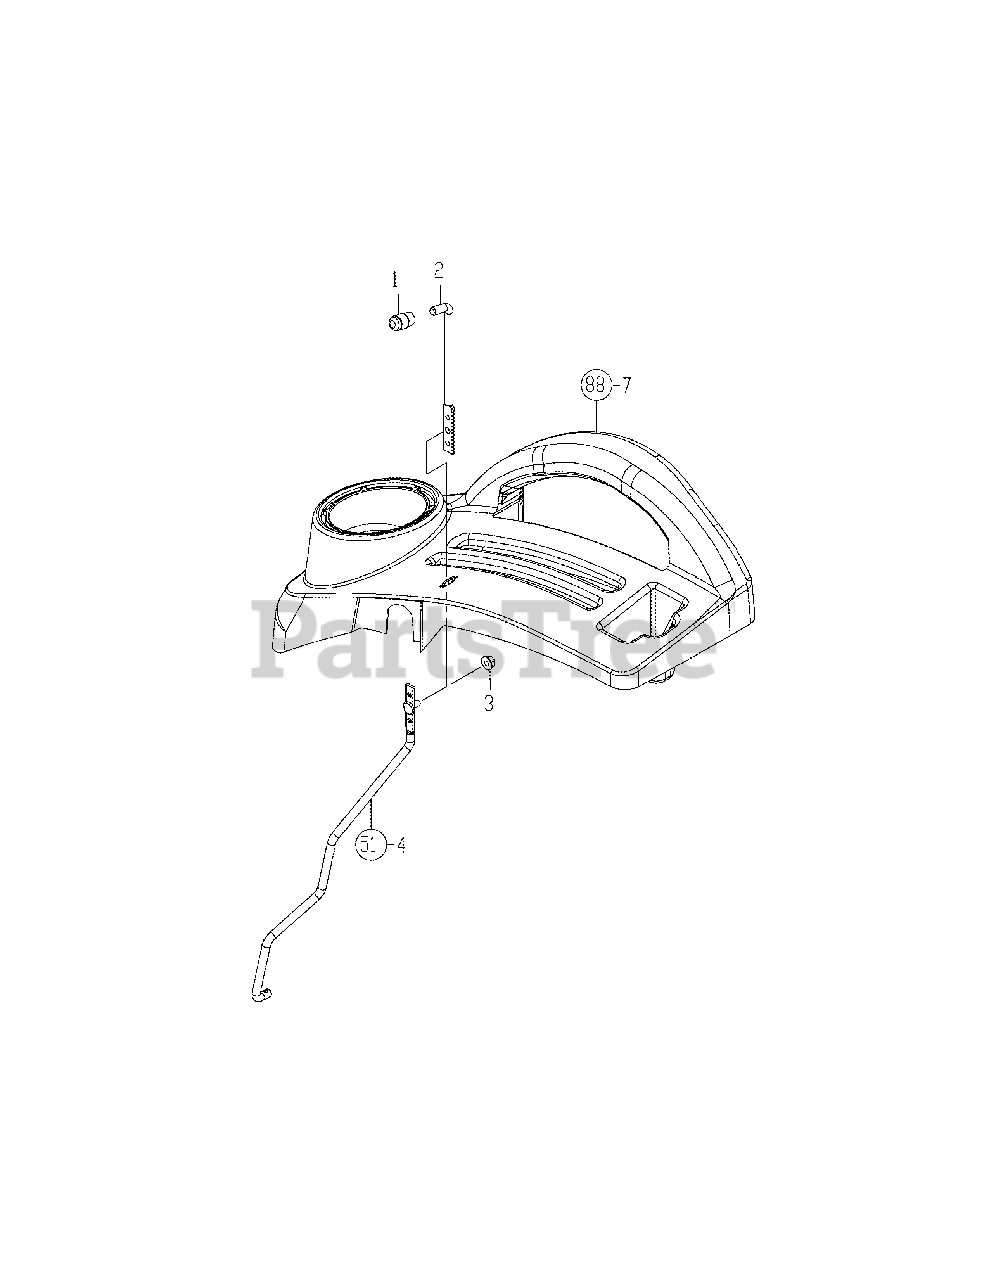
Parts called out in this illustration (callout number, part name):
2	Rod, C Cruise
2-1	Rod, C Cruise
3-1	Nut W/Washer 8
